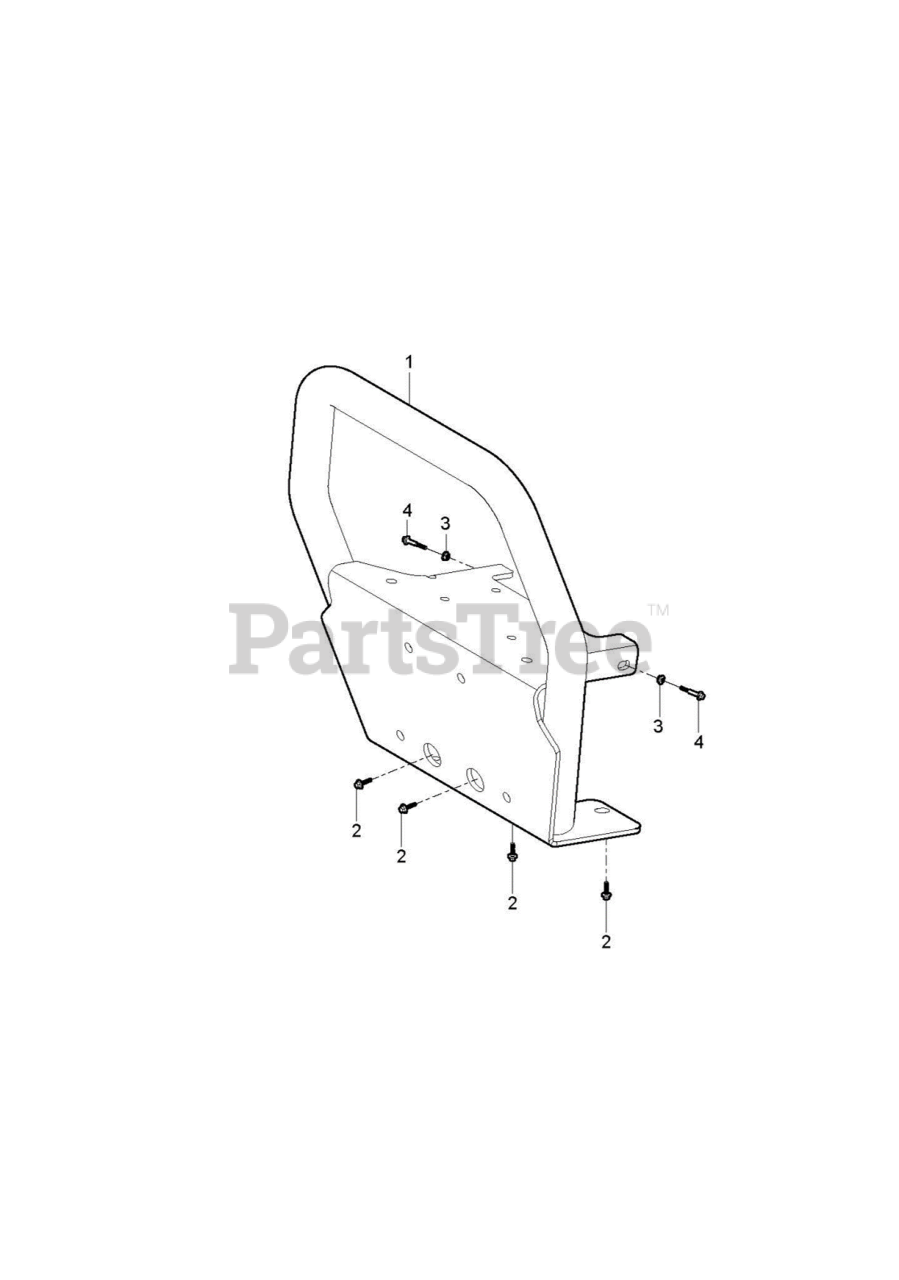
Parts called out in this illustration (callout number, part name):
1	BUMPER-FRONT
2	HEX HD FLANGE BOLT
3	LOCK NUT M10X1.25
4	HEX FLANGE BOLT M10X1.25X50
